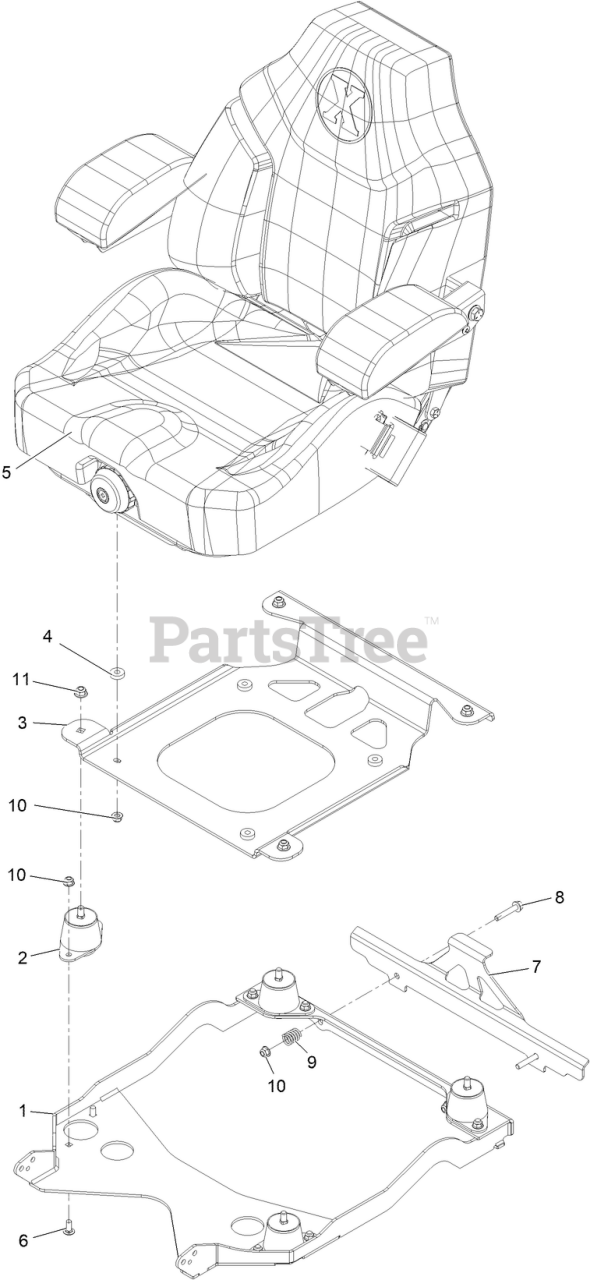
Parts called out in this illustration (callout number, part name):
1	Frame-Seat, Lower [black]
2	ISOLATOR-SEAT
3	Pan-Seat, Upper
5	ASM-SUSPENSION SEAT
6	SCREW-CARR
7	Latch-Seat
8	Screw-HWH
9	Spring-Compression
10	NUT-HF, NI
11	NUT-HF, NI
